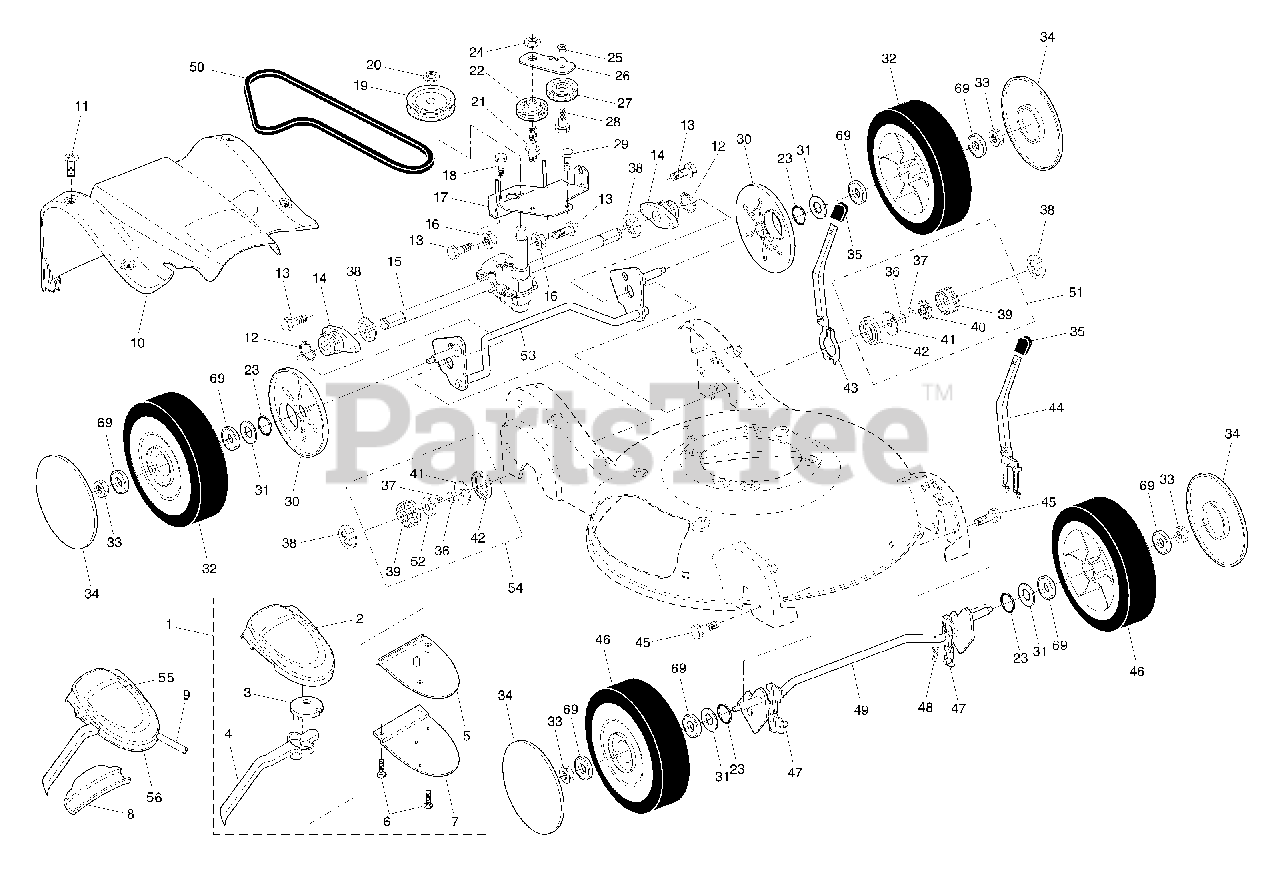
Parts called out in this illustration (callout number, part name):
1	Drive Control Assembly, Complete
2	Cover, Drive Control, Top
3	Pulley, Drive Control
4	Lever, Drive Control (blue)
5	Cover, Drive Control, Bottom
6	Screw, Torx Head #8 x 5/8
7	Bracket, Mounting, Drive Control
8	Cap, Drive Control, Bottom
9	Cable, Drive Control
10	Cover Assembly, Drive
11	Screw
12	Ring, Retaining
13	Screw
14	Bearing / Axle Support
15	Gear Case Assembly
16	Nut, Hex
17	Bracket, Gear Case / Drive Pulley
19	Pulley, Drive
20	Nut, Hex, Flangelock
21	Bolt, Idler
22	Pulley Assembly, V-Groove
23	O-Ring
24	Nut, Hex, Flangelock
25	Nut, Hex, Lock
26	Idler Arm
27	Pulley, Idler
28	Bolt, Hex Head, Shoulder
29	Screw 1/4-20 x 1/16
30	Cover, Dust, Wheel
31	Washer, Flat 3/8
32	Wheel Assembly, Rear 9 x 2-1/4
33	Nut, Hex
34	Hubcap
36	Spring, Torsion
39	Pinion, Gear
40	Retainer, Drive, LH
41	Disc, Drive
42	Seal, Friction
43	Lever, Selector, Wheel Height, Rear
44	Lever, Selector, Wheel Height, Front
46	Wheel Assembly, Front 9 x 2-1/4
47	Bushing, Front Axle
48	Retainer, Hairpin Cotter
49	Torque Shaft Assembly, Front
50	Belt, Drive
51	Pinion Assembly, LH
52	Retainer, Drive, RH
53	Rear Axle Assembly
54	Pinion Assembly, RH
55	Decal, Drive Control
56	Decal, Drive Control Adjustment (bottom)
69	Bearing, Ball (Wheel)
